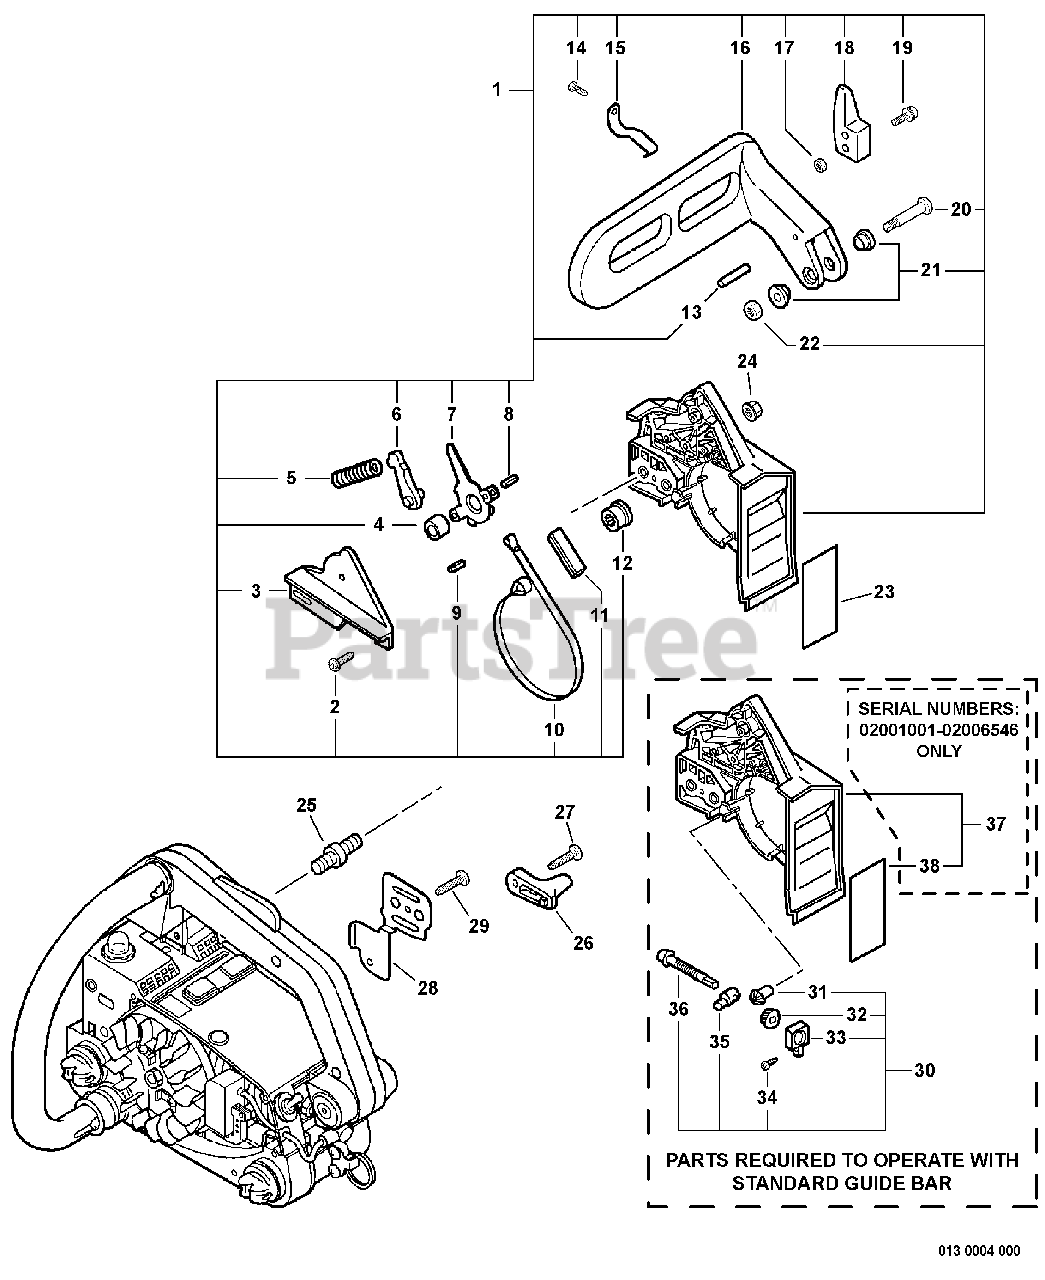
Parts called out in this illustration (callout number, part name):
1	CHAIN BRAKE ASSY
2	SCREW - 4X12 -- TAPPING
3	COVER, BRAKE - GRAY
4	SPACER - 8
5	SPRING, BRAKE
6	STOPPER, BRAKE
7	LEVER, BRAKE
8	PIN - SPRING -- 4X8
9	PIN - SPRING -- 2.5X12
10	BAND, BRAKE
12	ADJUSTER, BRAKE BAND
13	ROLLER - 4X23.8
14	SCREW - 4X10
15	SPRING, RETURN
16	LEVER, BRAKE - ORANGE
18	WEIGHT, BRAKE
19	SCREW - 4X20
20	SCREW - 5X32
22	LOCKNUT - 5
23	DEFLECTOR, HEAT
24	NUT - 6 -- FLANGE
25	STUD, GUIDE BAR
26	CATCHER, CHAIN
27	SCREW - 5X20 -- TAPPING
28	PLATE, GUIDE - OUTER
29	SCREW - 4X10
30	SIDE ADJUSTER KIT
31	GEAR - PINION
32	GEAR - BEVEL
33	BRACKET, TENSIONER
34	SCREW - 4X12 -- TAPPING
35	TENSIONER, CHAIN
36	SCREW, TENSIONER
37	GUARD, SPROCKET - GRAY
38	DEFLECTOR, HEAT
